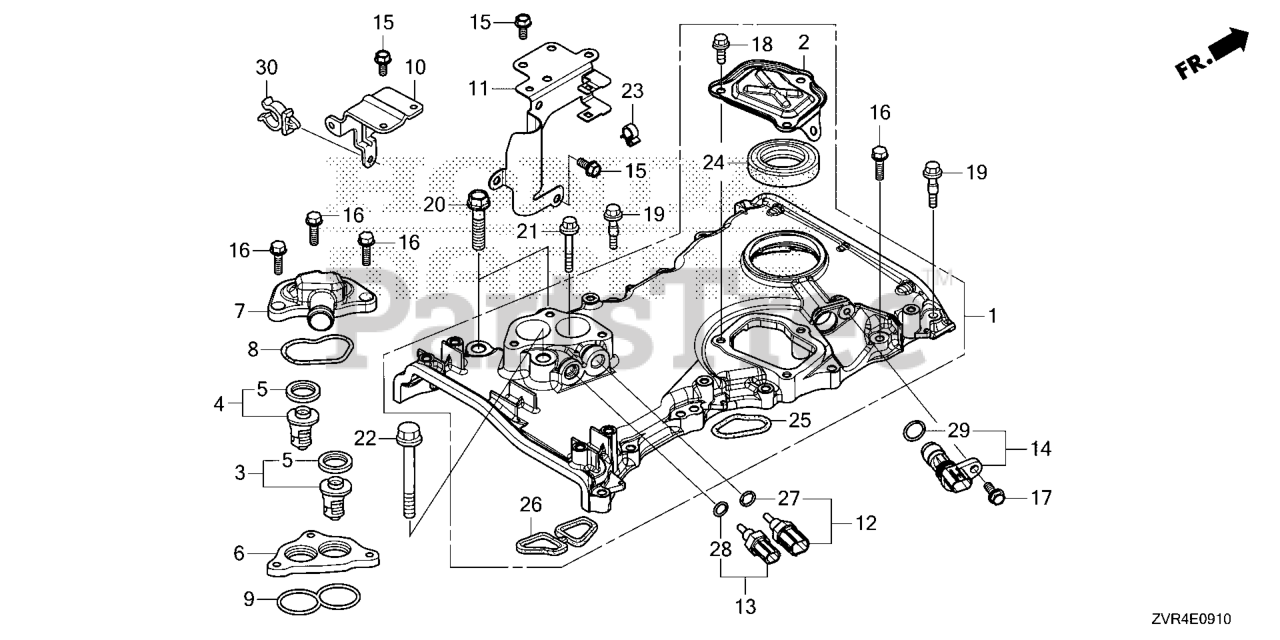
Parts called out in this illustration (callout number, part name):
1	CASE ASSY., CHAIN *NH8* (DARK GRAY)
2	COVER, CHAIN CASE
3	THERMOSTAT ASSY.
4	THERMOSTAT ASSY.
5	RUBBER, RING
6	SPACER, THERMOSTAT COVER
7	COVER, THERMOSTAT
8	GASKET, THERMOSTAT COVER
9	GASKET, THERMOSTAT SPACER
10	BRACKET B, HARNESS CLIP
11	BRACKET, HARN CLIP C
12	SENSOR ASSY., WATER TEMPERATURE
13	SENSOR ASSY., WATER TEMPERATURE
14	SENSOR ASSY., CRANK
15	BOLT, FLANGE (6X14) (CT200)
16	BOLT, FLANGE (6X28)
17	BOLT, FLANGE (6X16)
18	BOLT, FLANGE (6X14)
19	BOLT, SPECIAL (6X31)
20	BOLT, FLANGE (10X43)
21	BOLT, FLANGE (6X38)
22	BOLT, FLANGE (10X70)
23	CLIP B, CABLE
24	OIL SEAL (43X58X7) (ARAI)
25	O-RING, CHAIN CASE
26	GASKET, CHAIN CASE
27	O-RING (9.5X1.5) (HONDA KIKAKI)
28	O-RING (9.5X1.9)
29	O-RING (15X1.9)
30	CLAMP (18.5MM)
